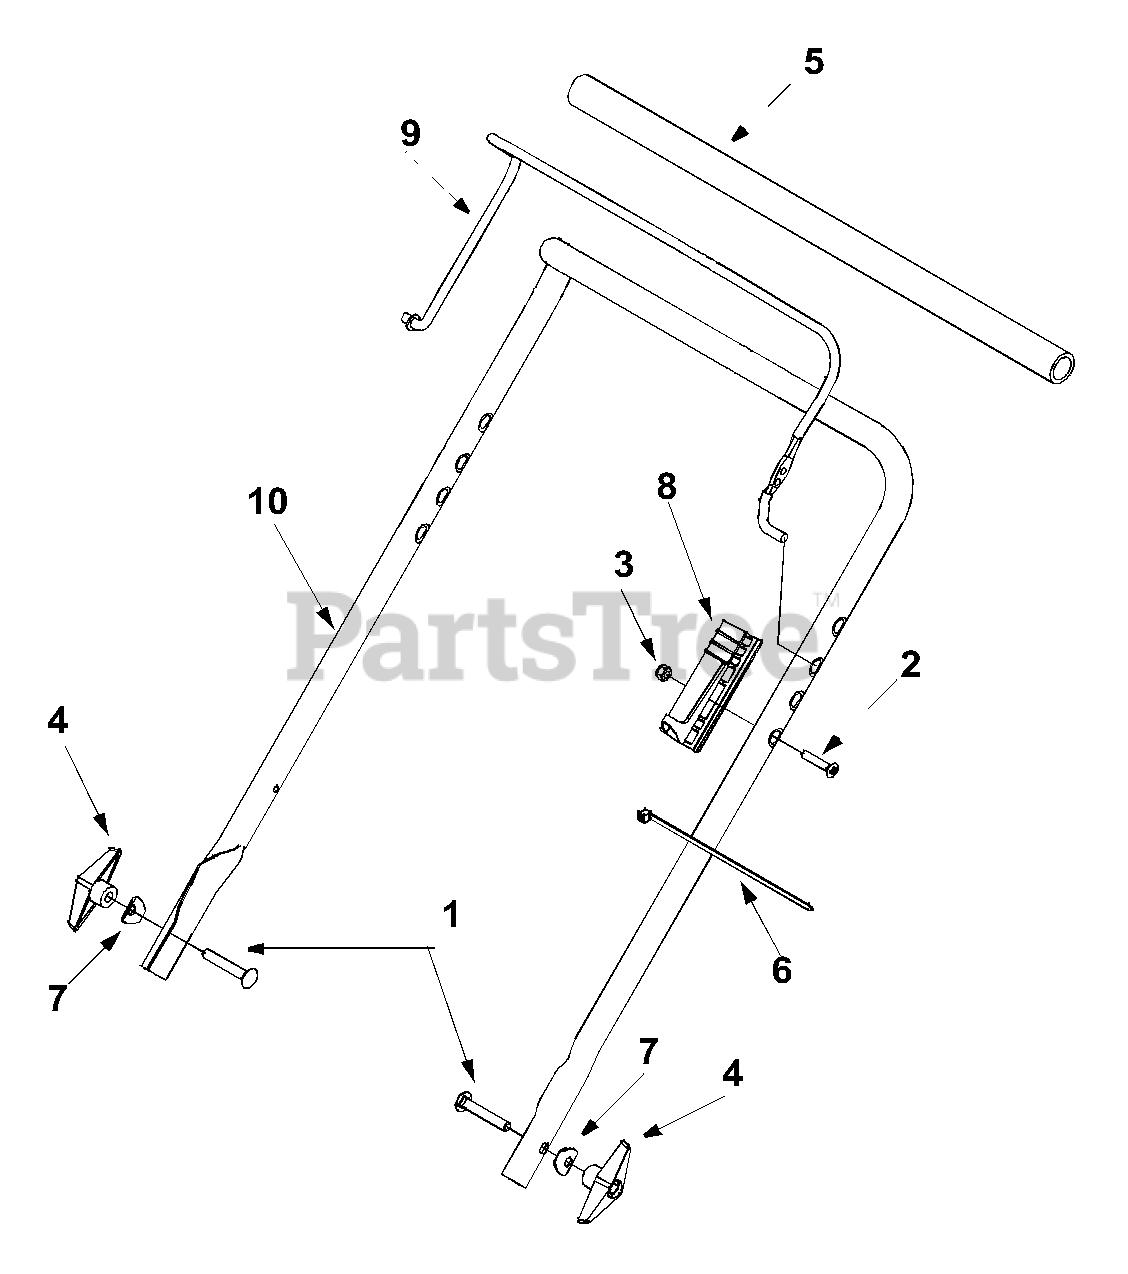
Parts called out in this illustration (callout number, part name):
1	Carriage Screw 5/16-18 x 2.0"
2	Machine Screw
3	Hex Lock Nut 1/4-20
4	Hand Knob w/ Wing Nut
5	Foam Grip
6	Cable Tie
7	Saddle Washer
8	Control Housing
